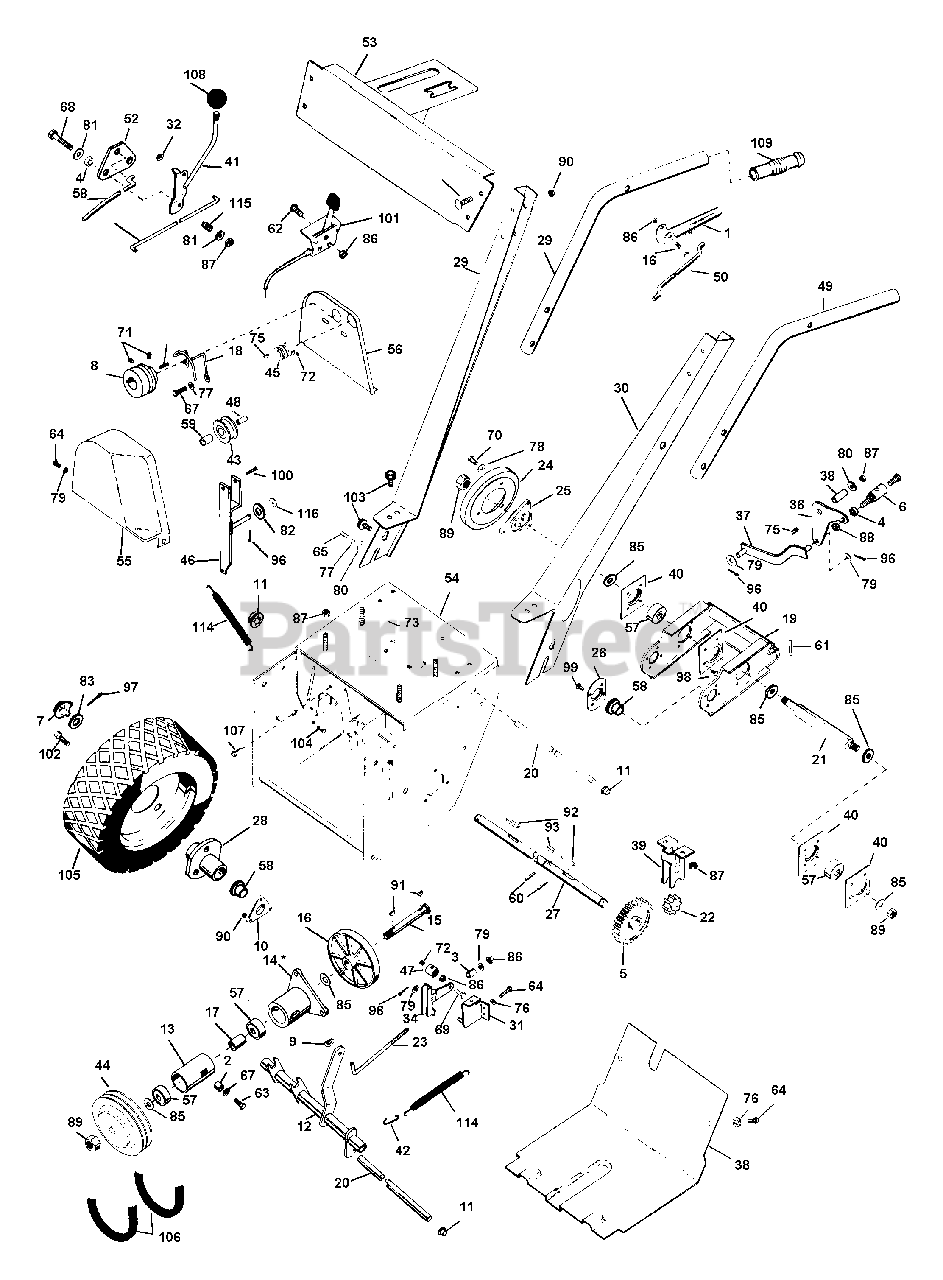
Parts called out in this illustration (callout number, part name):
1	CLUTCH HANDLE
4	SPACER BUSHING .5 X .32 X .21
5	SPUR GEAR, FELLOWS 35T .750 ID
6	BALL JOINT
7	HUB CAP
8	ENGINE SHEAVE
9	RATCHET PLATE
10	SUPPORT, BEARING
11	CAP, .50 ROD YWZC
13	SPINDLE HOUSING
14	DRIVE SPINDLE HOUSING
15	SPINDLE
16	DRIVE DISK
17	BEARING SPACER .75 X .5 X.88
18	BELT FINGER
19	CARRIER
21	HEX SHAFT
23	ADJUSTMENT LINK
24	FRICTION DISC
25	FRICTION DISC HUB
26	BEARING RETAINER
27	AXLE SHAFT
28	WHEEL HUB
29	R H LOWER HANDLE BAR
30	L H LOWER HANDLE BAR
31	DEADMAN BRACKET
32	SPRINGGRIP FASTENER
33	BSHG-SLV .334 X .502 X 1.437
34	DEADMAN LEVER
35	SHIFT ROD
36	SHIFT LEVER
37	SHIFT LINK
40	BEARING RETAINER
41	SHIFT HANDLE
42	SPRING HOOK
44	DRIVE SHEAVE
45	CAMSHAFT SHEAVE
46	IDLER ARM
47	ROD ADAPTER
48	IDLER SHAFT
49	HANDLE BARS
50	UPPER CLTCH ROD
51	LOWER CLTCH ROD
53	HNDLBR BRCKT
54	TRACTOR FRAME
55	OUTER BELT COVER
56	INNER BELT COVER
57	BRG-BALL .500X1.38X.437
58	BSHG-FLG .750X1.000X.625X1.250
59	BSHG-SLV .500X.625X.937
60	PIN-ROLL .125X1.00
61	PIN-ROLL .188X1.00
62	BLT-HEX .25-20X.75 PL GR2
63	BLT-HEX .31-18X1.00 PL GR 2
64	BLT-HEX .25-20X.50 PL GR2
65	BLT-HEX .31-18X.50 PL GR2
66	BLT-HEX .25-20X1.50 PL GR5
67	BLT-HEX .31-24X.75 PL GR5
68	BLT-HEX .31-18X1.75 PL GR2
69	BLT-HEX .25-20X.75 PL GR5
70	BLT-HEX .25-20X.38 PL GR2
71	SCR-SET .32-18X.38 SKHCUPNL OH
72	SCR-SET .25-20X.25 SKHCUPNY OH
73	BLT-RDHDSQSHNK .31-18X.50 YZ
74	BLT-RDHDSQNK .25-20X1.50 SHTPL
75	BLT-RDHDSQNK .31-18X2.0 SHT PL
76	WSHR-LK .250X.077 HVY PL
77	WSHR-LK .312X.097 PL HVY
78	WSHR-LK-EXT. 250 ID
79	WSHR-FL-STL .250X.562X.049 PL
80	WSHR-FL-STL .38X.875X.083 PL
81	WSHR-FL-STL.312X.734X.065PL
82	WSHR-FL-STL .281X1.250X.048PL
83	WSHR-FL-STL .755X2.000X.125
84	WSHR-FL-STL .505X.880X.072 PL
85	WSHR-FL-STL .505X1.000X.062
86	NUT-LK-CTR .250-20 PL
87	NUT-LK .312-18 GR A PL
88	NUT-LK-CTR .312-24 PL
89	NUT-LK-CTR .50-20 PL
90	NUT-LK-FLG .250-20 PL
91	KEY-WDRF .125X.500X.203 SAE 3
92	KEY-FTHR .188X1.25X.187 SAE
93	KEY-WDRF .25X.750X.313 SAE91
94	KEY-SQ .188X1.0X.188 SAE 8630
95	KEY-WDRF .125X.625X.250 SAE5
96	PIN-COTR .09X.75 PL
97	PIN-COTR .12 X 1.25 PL
98	RVT-POP .187X.402 DOME ST
99	RVT-POP.125 X .294 DOME
100	RVT-TBLR .187X1.343 OH ST YZWC
101	THROTTLE CONTROL
102	BLT-WHL .50-20X.50 GR5 PL
103	BLT-SERHFWH .31-18X.50 PL
104	SCR-SLTR-SERNK .25-20X.62 PL
105	WHL 10.25 IN O.D.
106	V-BELT, SPECIAL-RAW EDGE (SET)
107	SCR-TAP .312-18X.50 CRPH PL 1A
108	SHIFT BALL
109	GRIP
110	4 HP ENGINE DECAL
111	CAUTION DECAL
112	SHIFT DECAL
113	HANDLEBAR DECAL
114	SG-TENS .063X.44X2.81 WLD 18
115	SG-COMP .092X.375X2.53
